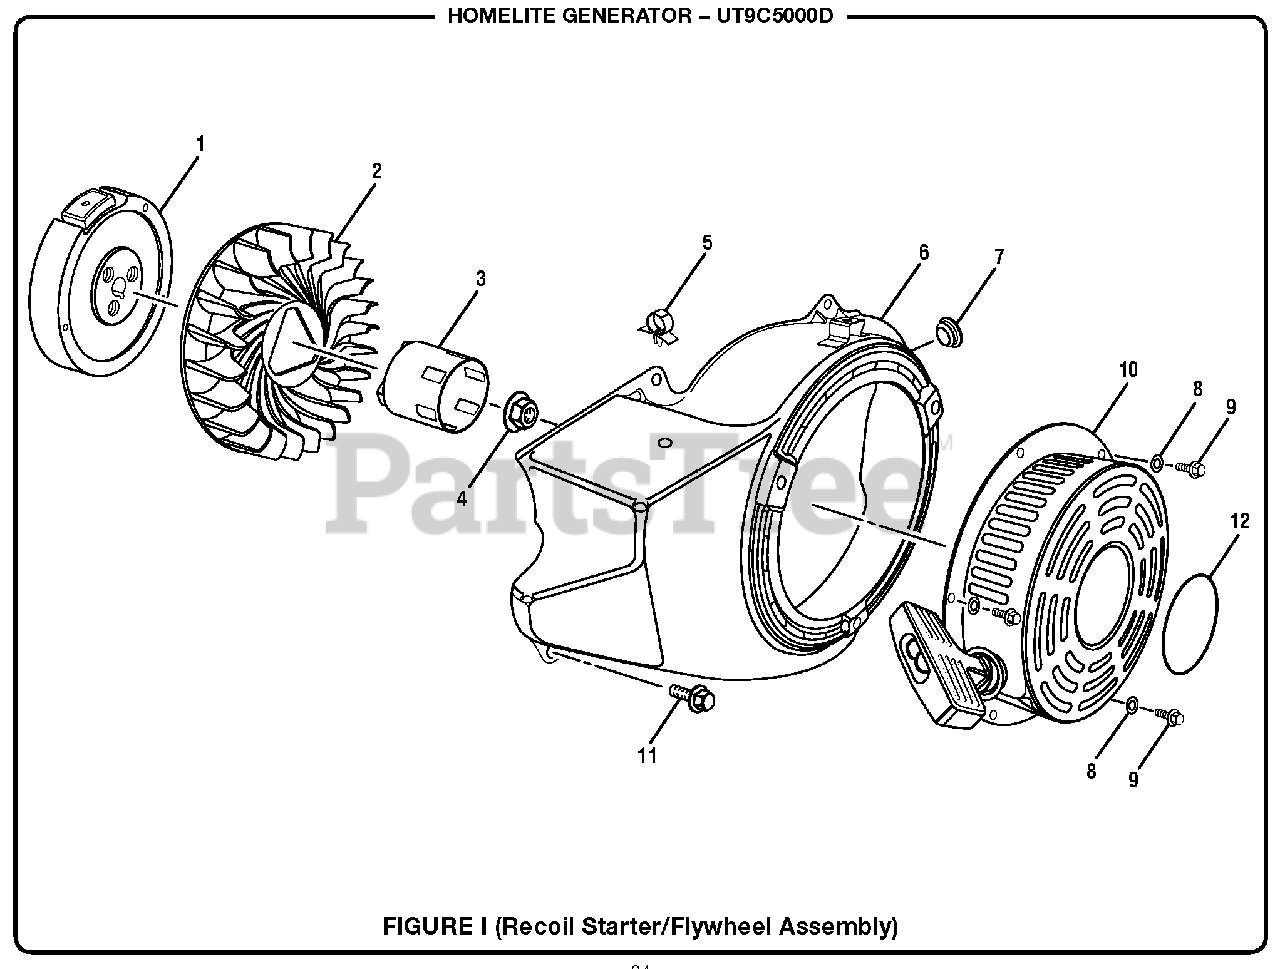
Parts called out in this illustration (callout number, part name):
2	Flywheel Fan
3	Starter Cup
4	Nut (M14 x 15 mm)
5	O-Ring (Fan Case)
6	Fan Case Assembly
7	Grommet (Fan Case)
8	Washer (M6)
9	Bolt (M6 x 8 mm, Flange Hd)
10	Recoil Starter Assembly
11	Bolt (M6 x 12 mm, Flange Hd)
12	Engine Recoil Label
